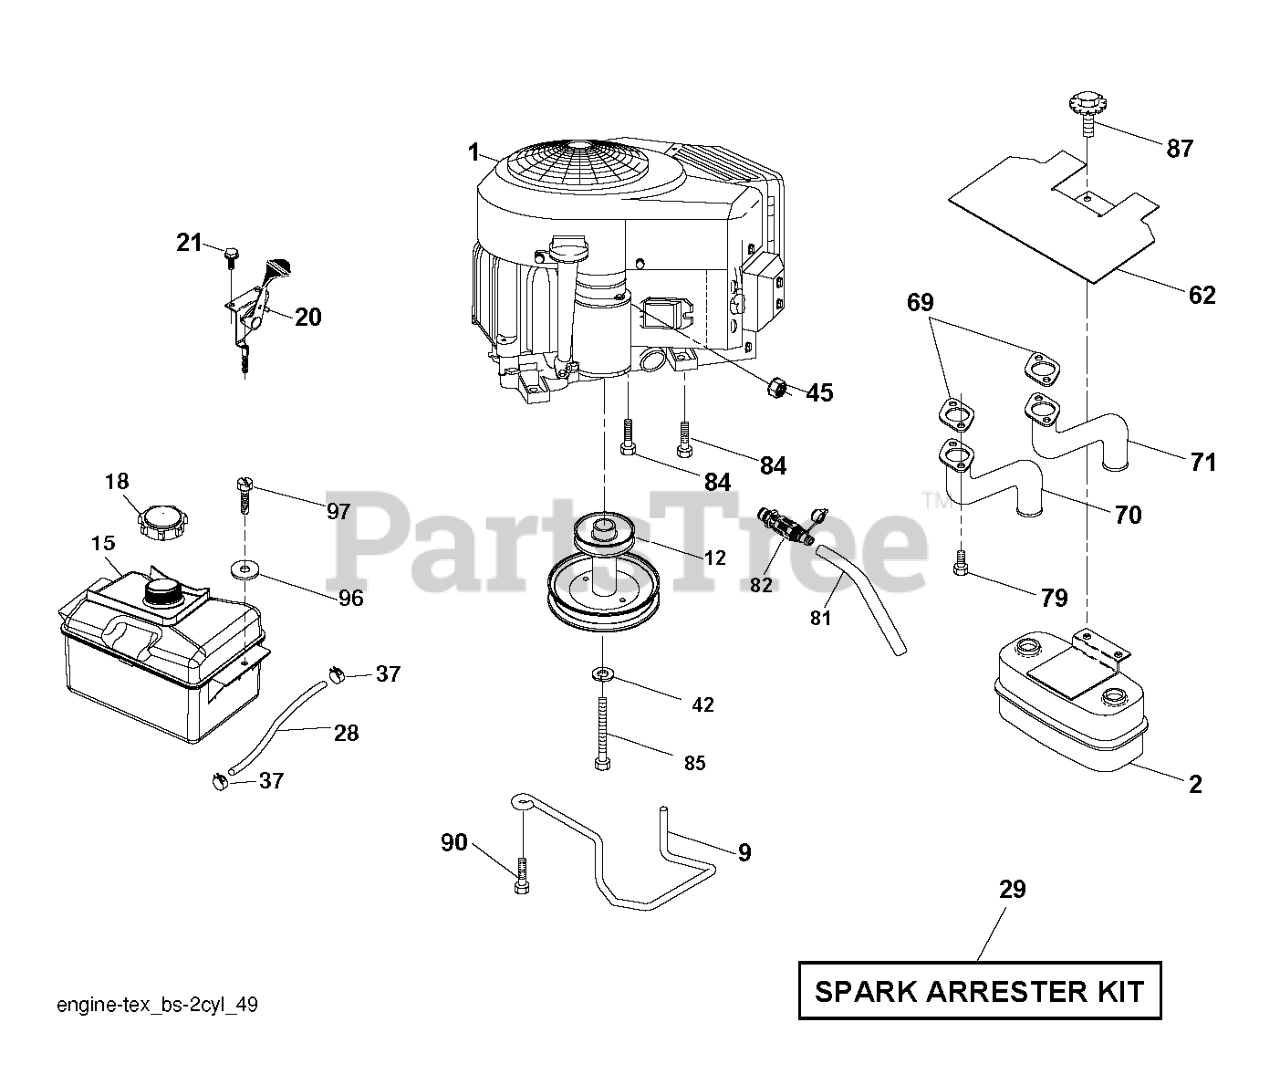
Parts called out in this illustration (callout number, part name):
2	MUFFLER.TWIN.CYL.LOW.TONE
9	KEEPER.BELT.ENGINE.4.2
12	PULLY ENGINE
15	TANK.ASM.FUEL.FR.2.5GA.
18	CAP ASM.FUEL.2.25"FR.
20	CONTROL.TH/CK.COBRA.B&S.TWN.BK
21	SCREW.#10 X 0.750.BOS
28	LINE.FUEL.20"FRONT.EMI
29	KIT.SPARK ARRESTOR 794945 B&S
37	HOSE CLAMP
42	LOCKWASHER
45	NUT
62	SHIELD.HEAT.MUFFLER
69	GASKET.MUFFLER
70	EXHAUST.TUBE.LH.BS/TWIN
71	EXHAUST.TUBE.RH.B&S.TWIN.INTEK
79	SCREW.SOCKET.HEAD.5/16-18
81	TUBE, DRAIN OIL ASM.
82	VALUE.OIL.DRAIN
84	SCREW.3/8-16
85	BOLT HEX 7/16-20X4-1/4"
87	BOLT.5/16-18UNCX3/4 W/SEMS.BLK
90	SCREW 3/8-16X1
97	SCREW HEXWSHR 1/4-20X3/4
